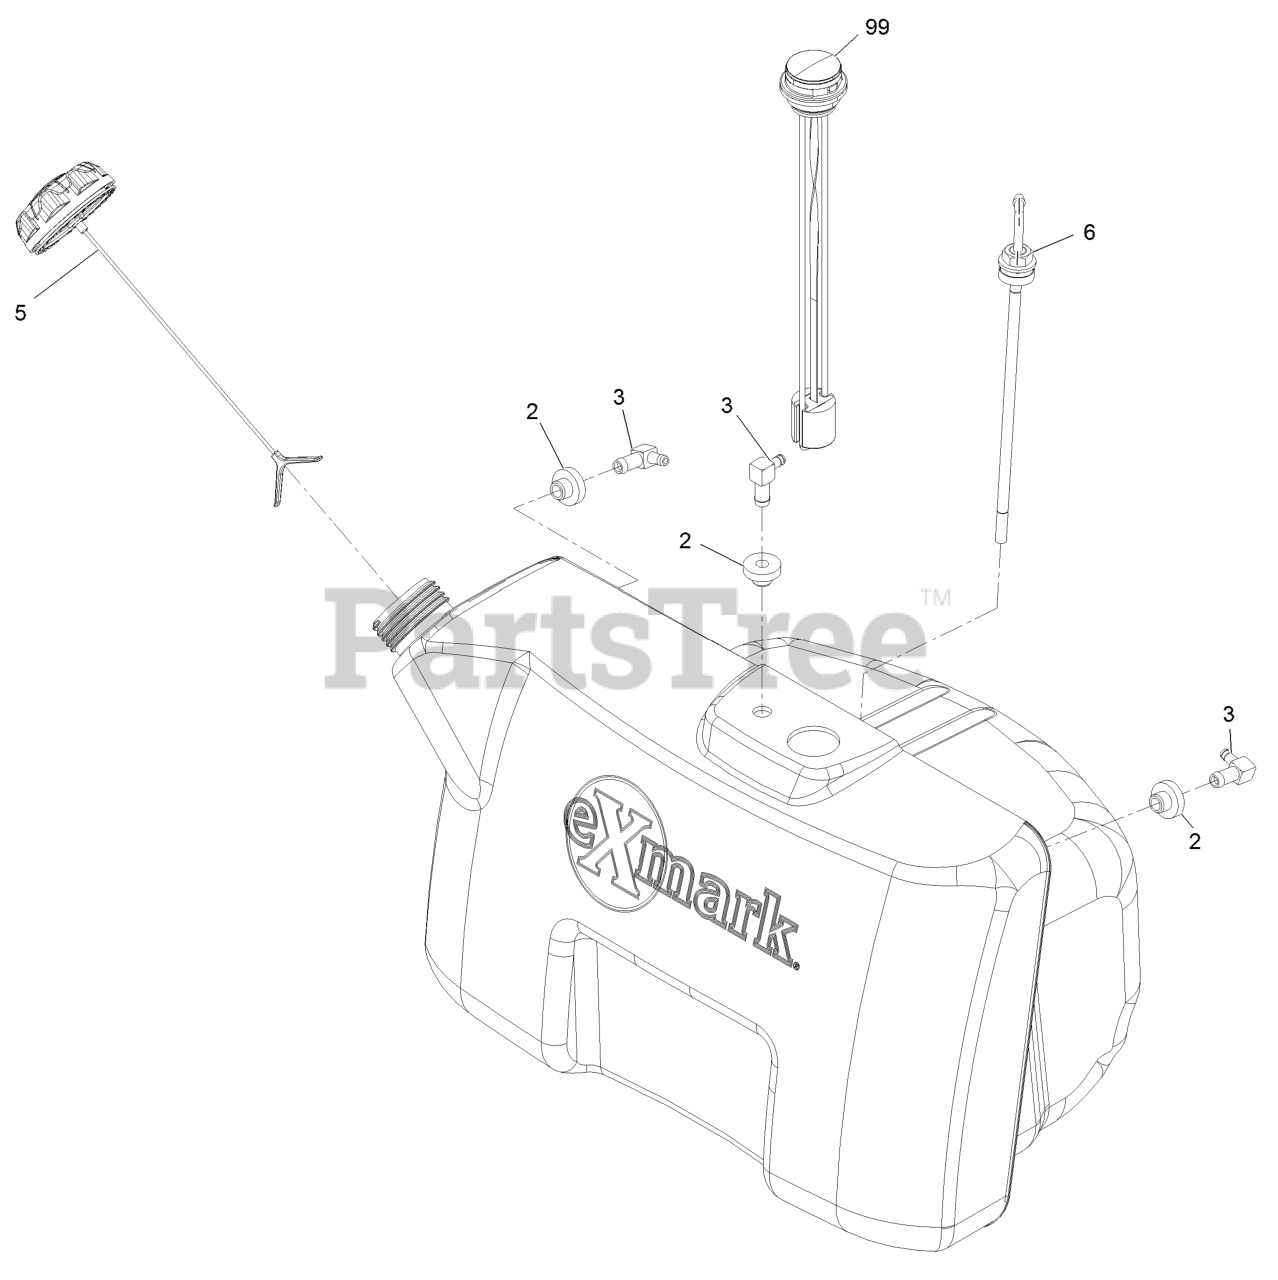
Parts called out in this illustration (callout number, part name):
2	BUSHING
3	ELBOW-90 DEG
5	CAP-FUEL, RATCHETING
6	FITTING-FUEL, BULKHEAD
99	FUEL GAGE REPLACEMENT KIT
